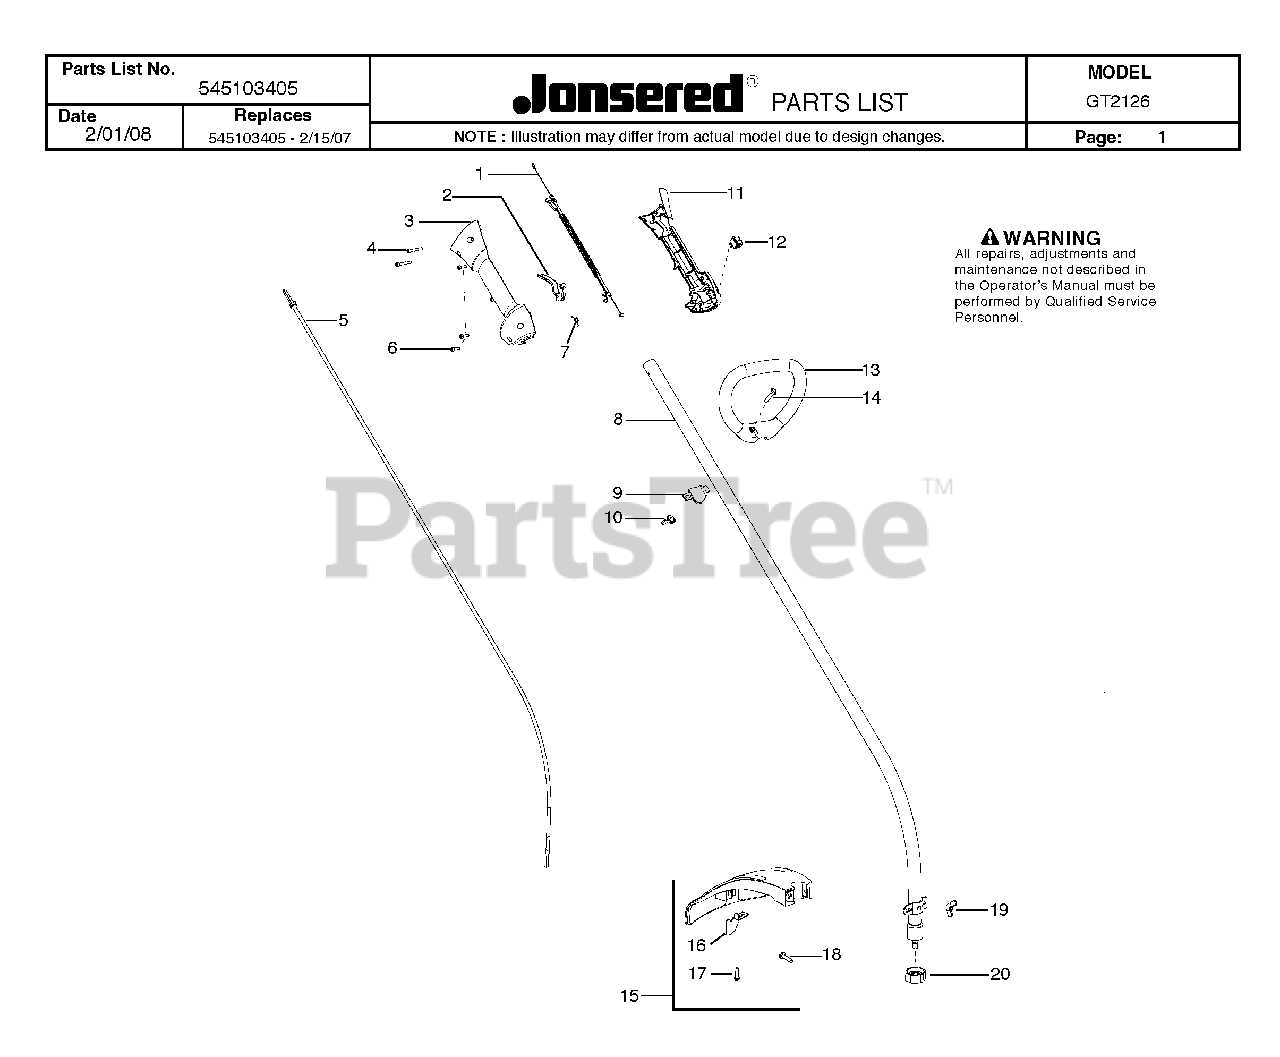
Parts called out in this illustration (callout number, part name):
6	SCREW M4 X 1.75 PT 16MM
7	SPRING TRIGGER
8	DRIVESHAFT KIT
9	CLAMP ASSIST HANDLE
10	WINGNUT, TYPE 2
12	KIT SWITCH
13	HANDLE ASSIST
14	BOLT, TYPE 2
15	KIT SHIELD
16	KIT - LIMITER - LINE
18	BOLT, TYPE 2
19	WINGNUT, TYPE 2
